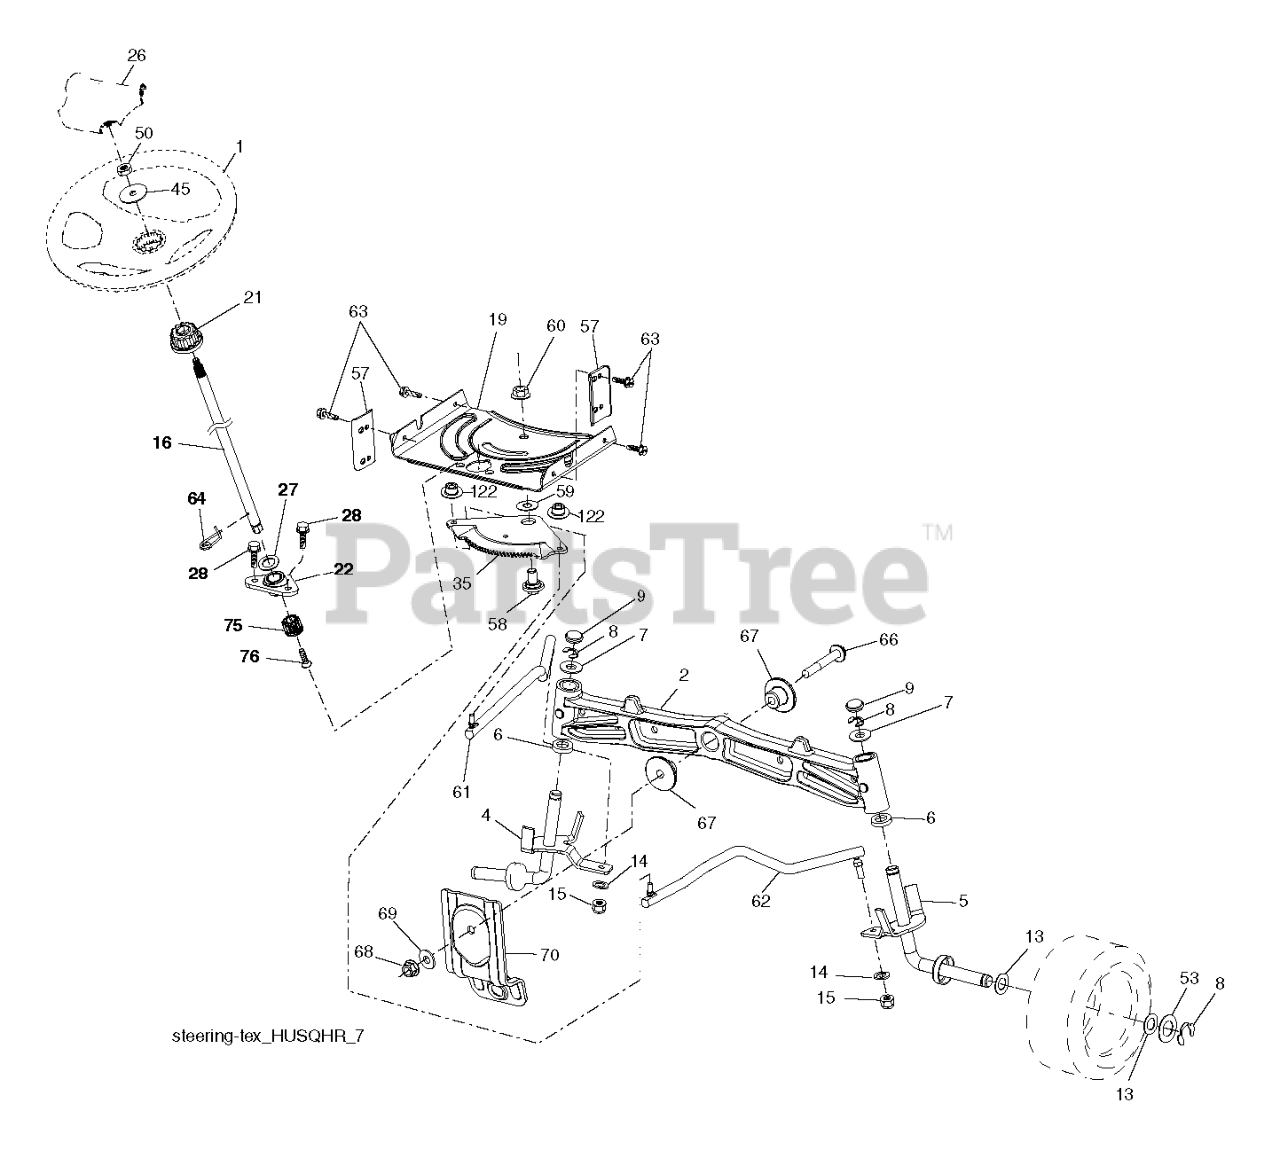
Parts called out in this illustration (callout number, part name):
1	WHEEL.STEERING.HUSQ.PREM.HRDRM
1	Service Kit
2	AXLE.CAST.IRON
4	SPINDLE.WELDED.LH.15"TEX
5	SPINDLE.WELDED.RH.15"T
6	WASHER THRUST
9	CAP.SPINDLE.BLACK
15	NUT CROWNLOCK 3/8-24
16	KIT.SRVC.STEERINGSHAFT.2HISHFT
16	SHAFT.STEER.2HIGH.SPLND.PLATED
19	PLATE.STEER.DDL.NLT/NG
21	KIT.SRVC.STEERINGSHAFT.ADAPTER
21	ADAPTER.WHEEL.STEER.SPLND.ALUM
22	BEARING.SHAFT.STEER.LOWER.625
26	INSERT.CAP.WHL.STRG.HUSQ.PREM
28	SCREW, 3/8-16X3/4
35	GEAR.SECTOR.PLATE.DDL.
45	WASHER.3/8ID.2-3/8OD.12GA.PLTD
50	NUT LOCK FLG 3/8-16 UNC
53	WASHER.HARDENED
57	BRACKET.UPSTOP.TEX
58	BOLT.SHOULDER.SECTOR.P
59	WASHER.THURST.SECTOR.S
60	NUT FLANGE LOCK 5/8-11
61	Links
62	Links
63	SCREW
64	RETAINER.CLIP.SPRING.S
66	BOLT HEX FGHD 7/16-14 X 3 SERR
67	BUSHING.PM.FRONT AXLE
68	NUT.LOCK.FLANGE.7/16
69	WASHER.1.5X.505X.118
70	BRACKET.FRT.DECK.SUSP.RR.MT431
75	PINION.ZINC PLATED
76	SCREW HEAD SOCKET LRVB
122	CAP.GEAR.SECTOR.TEX
